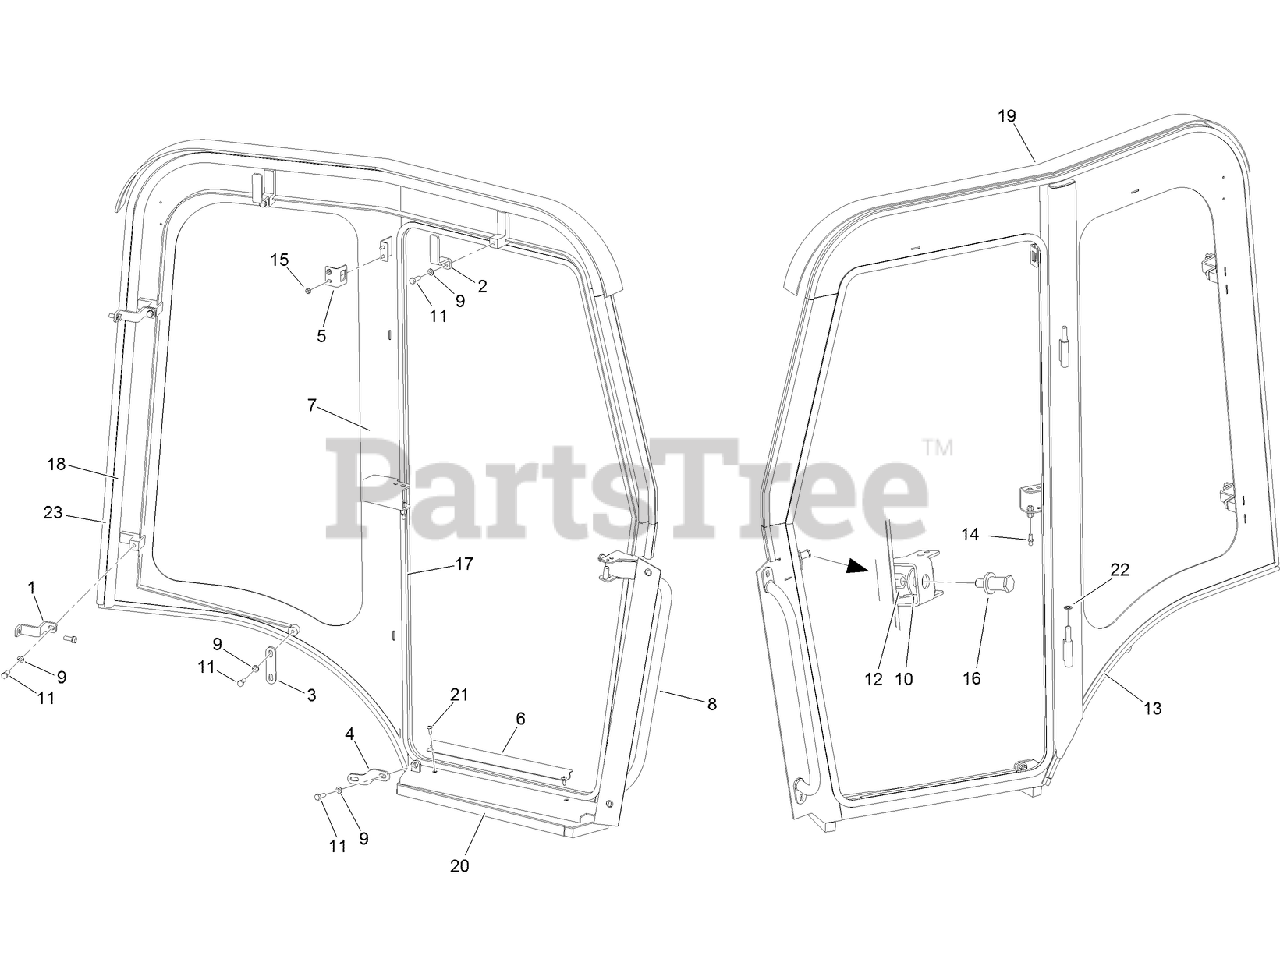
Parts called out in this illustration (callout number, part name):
1	BRACKET-MOUNT, SIDE PANEL
2	BRACKET-MOUNT, SIDE PANEL
3	STRAP-MOUNT, SIDE PANEL
4	STRAP-MOUNT, SIDE PANEL
5	COVER-SWITCH, LH
6	BRACKET-SEAL, TRIM
7	PANEL-SIDE, LH
8	HANDLE-GRAB
9	WASHER-LOCK
10	WASHER-FLAT
11	BOLT-HHCS
14	STUD-BALL, GAS SPRING
15	NUT-HEX
16	STUD STRIKER ASM
17	SEAL-RUBBER
18	SEAL-RUBBER
19	SEAL-FLAP
20	SEAL-STRIP
21	SCREW-TORX
22	WASHER-HINGE, BRASS
23	SEAL-CLIP ON
